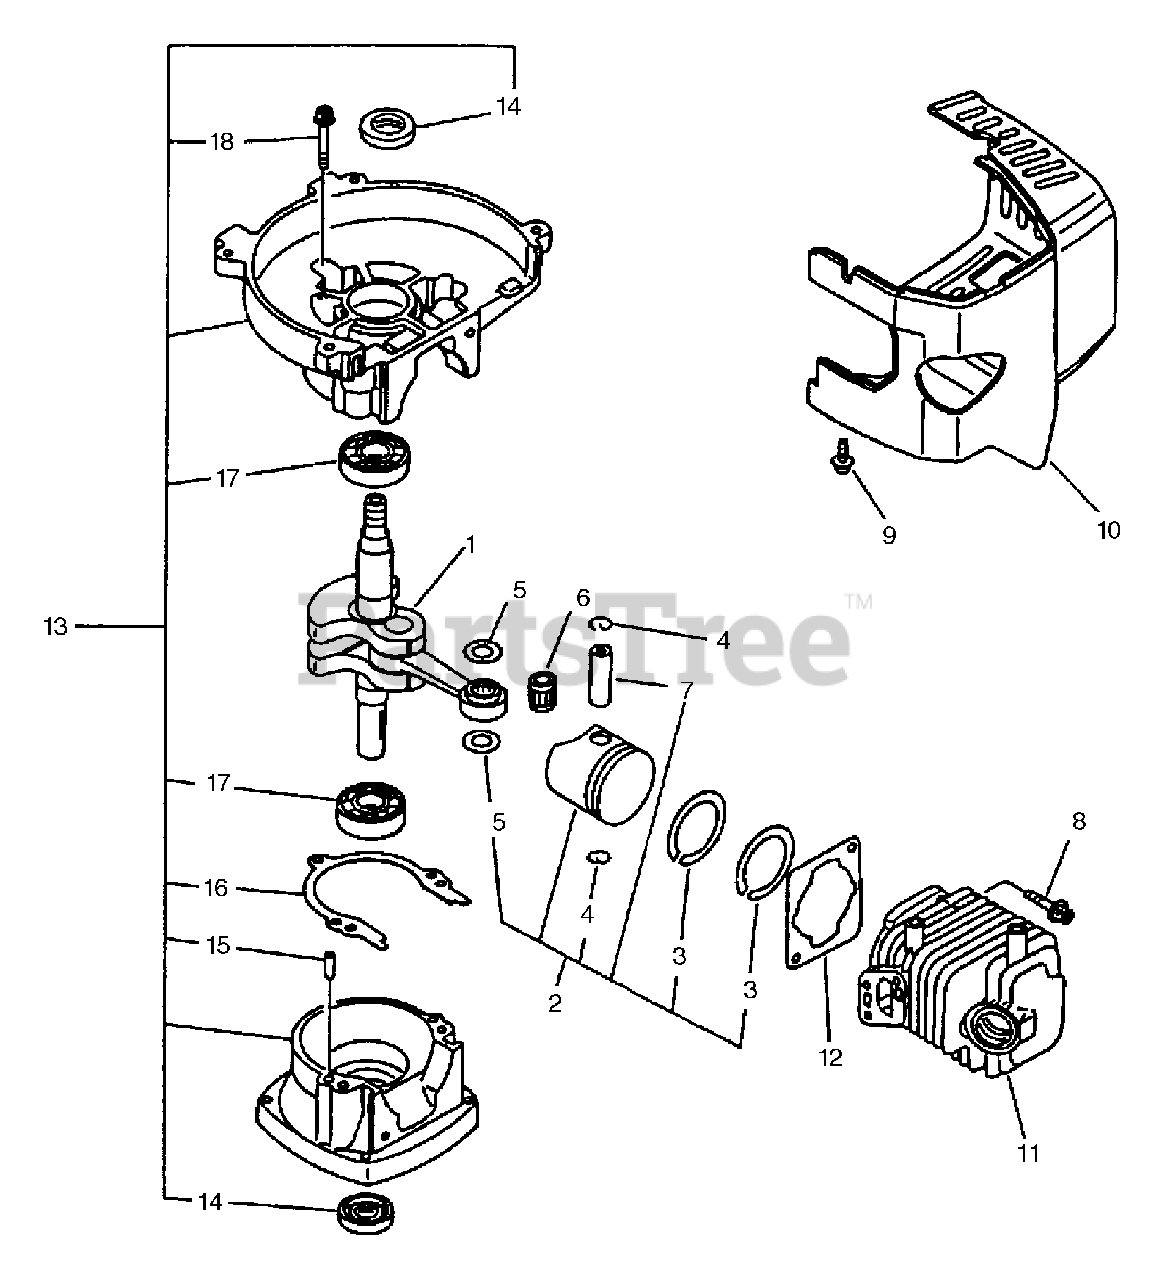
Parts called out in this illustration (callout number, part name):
1	CRANKSHAFT ASSY
2	PISTON KIT
3	RING, PISTON
4	RING, SNAP
5	WASHER, THRUST
6	BEARING, NEEDLE
7	PIN, PISTON 8
8	BOLT 5×22
9	BOLT 4×20
10	COVER, CYLINDER
11	CYLINDER
12	GASKET, CYLINDER
13	CRANKCASE SET
14	SEAL, OIL 12
15	PIN, LOCATING 4
16	GASKET, CRANKCASE
17	BEARING, BALL - 6201 C3
18	BOLT 5×28
